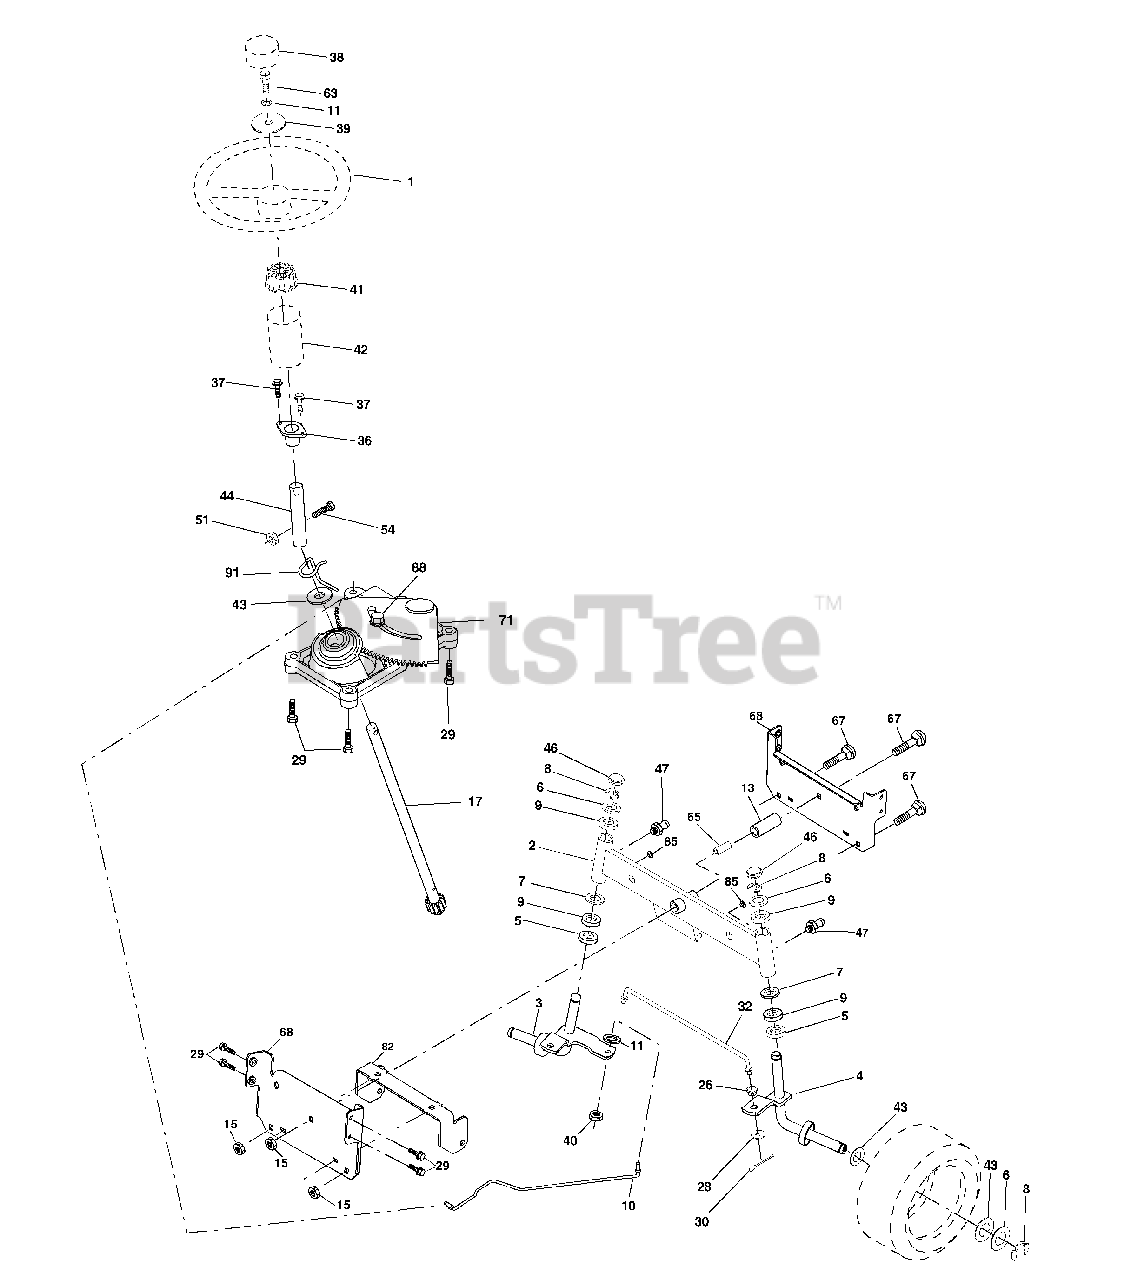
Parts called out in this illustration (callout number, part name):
1	Wheel Steering Auto Black
2	Axle Asm Front
3	Spindle Asm Lh
4	Spindle Asm Rh
5	Bearing Race Thrust Harden
6	Washer 25/32 X 1 5/8 X 16ga
7	Washer 27/32 X 1 1/4 X 16 Ga
8	Ring Klip #t5304-75
9	Bearing Col Strg Blk
10	Link Drag
11	Lockwasher
13	Spacer Bearing Axle Front
15	Hex Flange Lock
17	Shaft Asm Strg
26	Bushing Rod Tie Blk Lt
28	Washer 13/32 X 7/8 X 16ga
29	Screw 3/8-16x3/4
30	Pin
32	Rod Tie Wire Form 19 75 Mech
36	Bushing Strg 5/8 Id Dash
37	Screw TT #10-32 x 5 x 3/8 Flange
38	Insert Cap Strg
39	Washer 13/32 x 2-3/8 x 12Ga
40	Locknut Center
41	Adaptor Wheel Strg 640/ 635id
42	Boot Dash Steering
43	Washer 25/32 X 1 1/4 X 16 Ga
44	Extension Steering Non-Adjust
46	Cap Spindle Fr Top Blk
47	Fitting Grease
51	Nut Lock Hex W/Ins.
54	Bolt Fin Hex 5/16-18 Unc P
63	Bolt Fin Hex 3/8-16unc x Gr. 5
65	Spacer Brace Axle
67	Bolt Rdhd Sq 3/8-16 Unc x 2-3/4
68	Brace Axle
71	Steering Asm
82	Bracket Susp Chassis Front
85	Fastener Christmas Tree
88	Bolt Shoulder 7/16-20 Unc
91	Clip Steering
